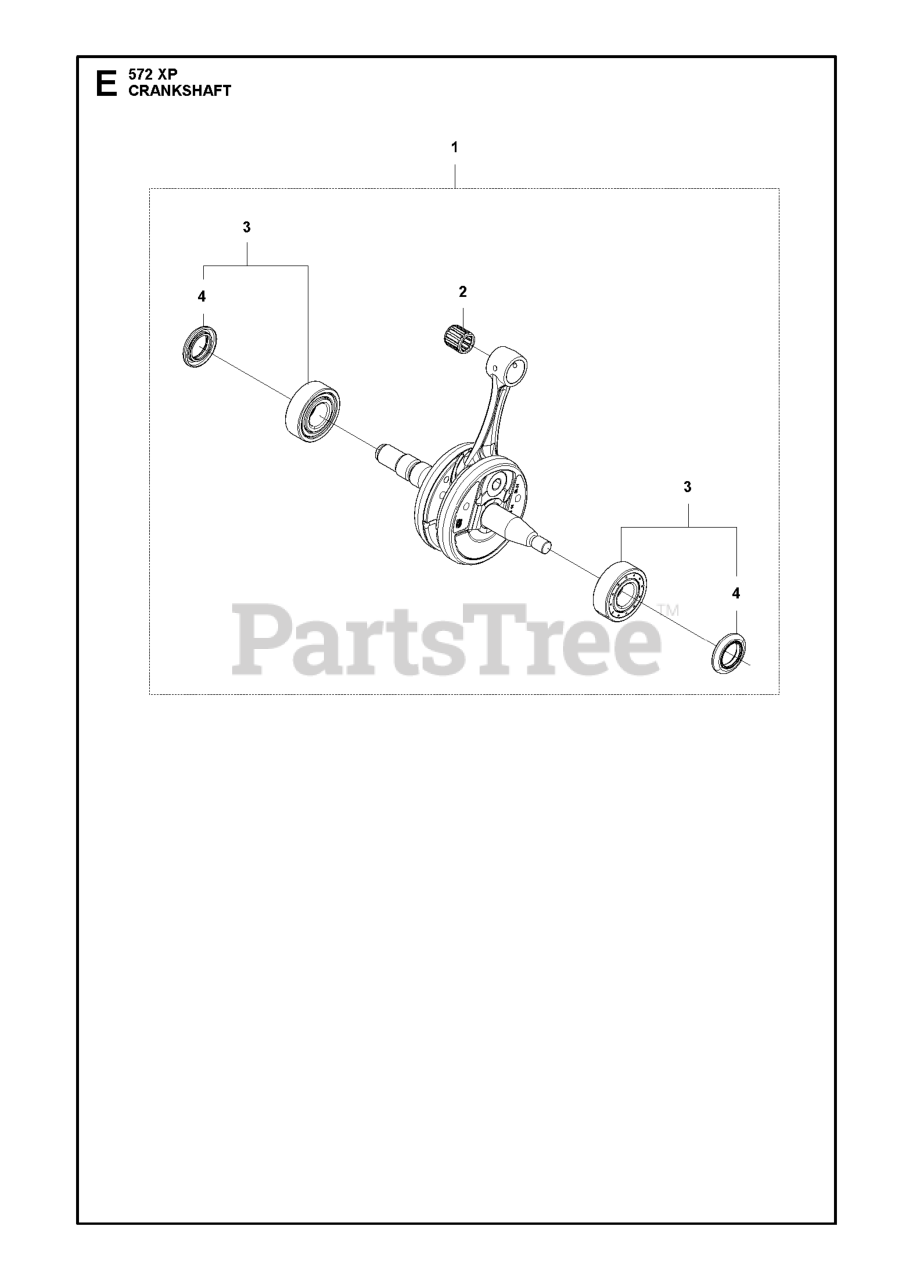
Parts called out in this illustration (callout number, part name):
1	CRANKSHAFT ASSY H572 SPARE PAR
2	NEEDLE BEARING PISTON PIN 12X1
3	BALL BEARING 6203/W12.5/D39-C4
4	RADIAL SEAL 24.5X32.7X3
